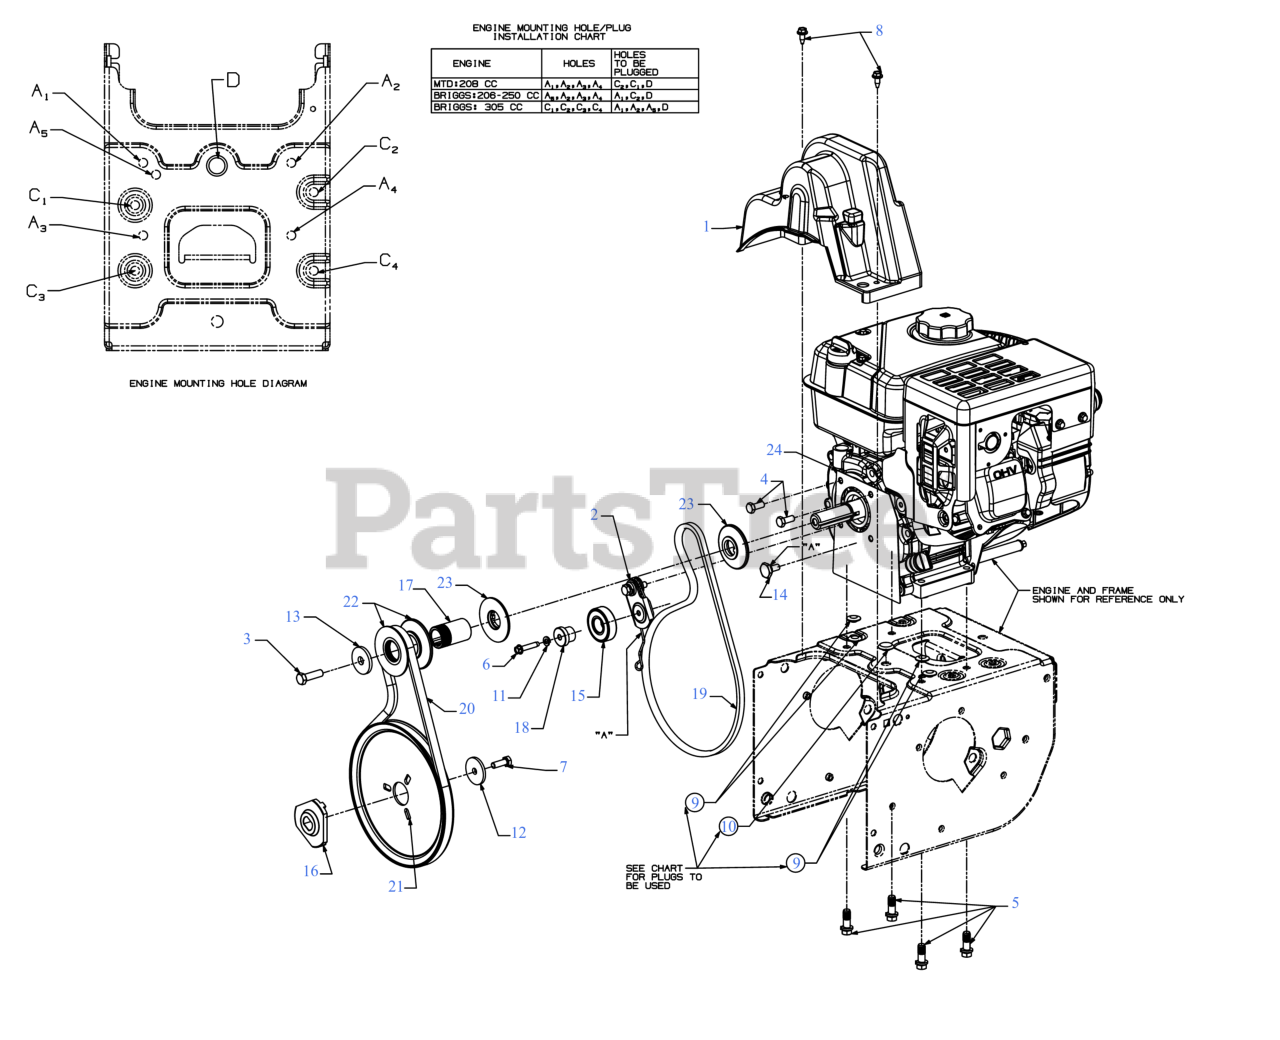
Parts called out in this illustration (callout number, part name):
1	BELT COVER (SMALL BLOCK)
3	SCREW 3/8-24X1.25
4	SCREW 5/16-24 x .750 GR5
5	SCREW 3/8-16 x 1
6	SCREW 1/4-20 x 1.25
7	SCREW 5/16-24 x .875 GR5
8	SCREW 1/4-20X.625
9	PLUG-3/8 DIA ID x 3/32
10	PLUG-1/2 ID x 3/32
11	LOCK WASHER
12	FLAT WASHER
13	FLAT WASHER .45 x 1.5 x .172 HT
14	SHOULDER SCREW
15	BALL BEARING
16	ADAPTER PULLEY .75 DIA W/DD
17	PULLEY SPACER
18	SHOULDER SPACER
19	V-BELT 3/8 x 35
20	V-BELT .500 x 35.00LG
20	Cub Cadet AUGER BELT
20	Genuine Factory Parts AUGER BELT
21	AUGER PULLEY
22	HALF PULLEY 4L V x 2.6 OD
23	HALF PULLEY 3/8-V x 2.2
24	COVER PLATE (POWDER BLACK)
